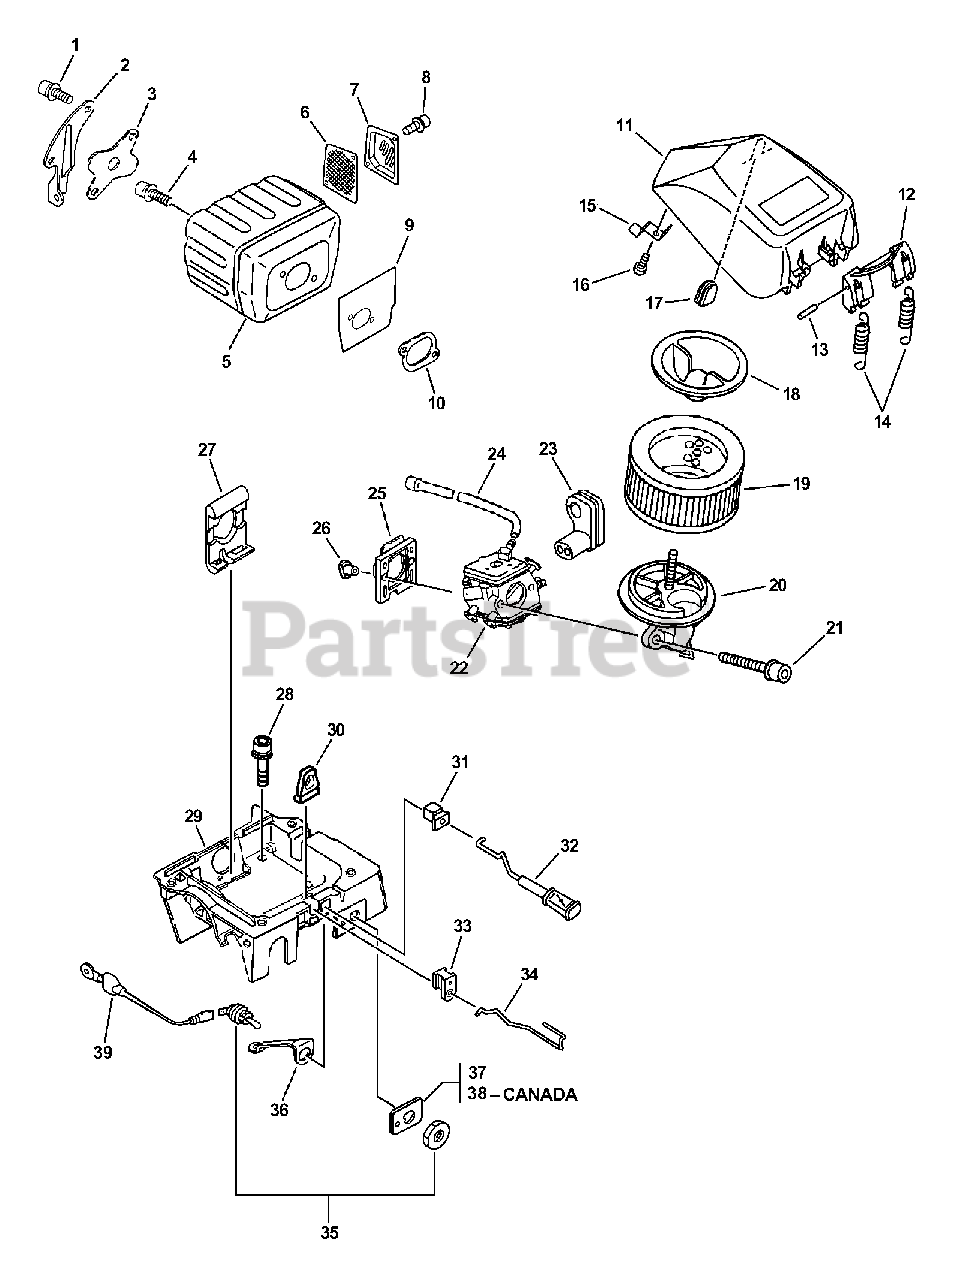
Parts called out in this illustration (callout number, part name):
1	BOLT 5×14
2	BRACKET, MUFFLER
3	COVER, MUFFLER
4	BOLT 5×20
5	MUFFLER
6	SCREEN, SPARK ARRESTER
7	GUIDE, EXHAUST
8	BOLT 4×10
9	HEAT SHIELD, EXHAUST
10	GASKET, EXHAUST
11	COVER, AIR FILTER
12	LATCH, FILTER COVER
13	PIN 3×12
14	SPRING, TENSION
15	SPRING, FLAT
16	SCREW 4×10
18	COVER, AIR FILTER
19	FILTER, AIR
20	MOUNT, AIR FILTER
21	BOLT, FLANGE
22	CARBURETOR
23	GROMMET, NEEDLE
24	PIPE, IMPULSE
25	INSULATOR, INTAKE
27	CUSHION
28	BOLT 5×20
29	CASE, CARBURETOR
30	CUSHION
31	GROMMET, CHOKE
32	ROD, CHOKE
33	GROMMET, THROTTLE ROD
34	ROD, THROTTLE
35	SWITCH, ON-OFF
36	PLATE, GROUND
37	LABEL, STOP
38	LABEL, STOP
